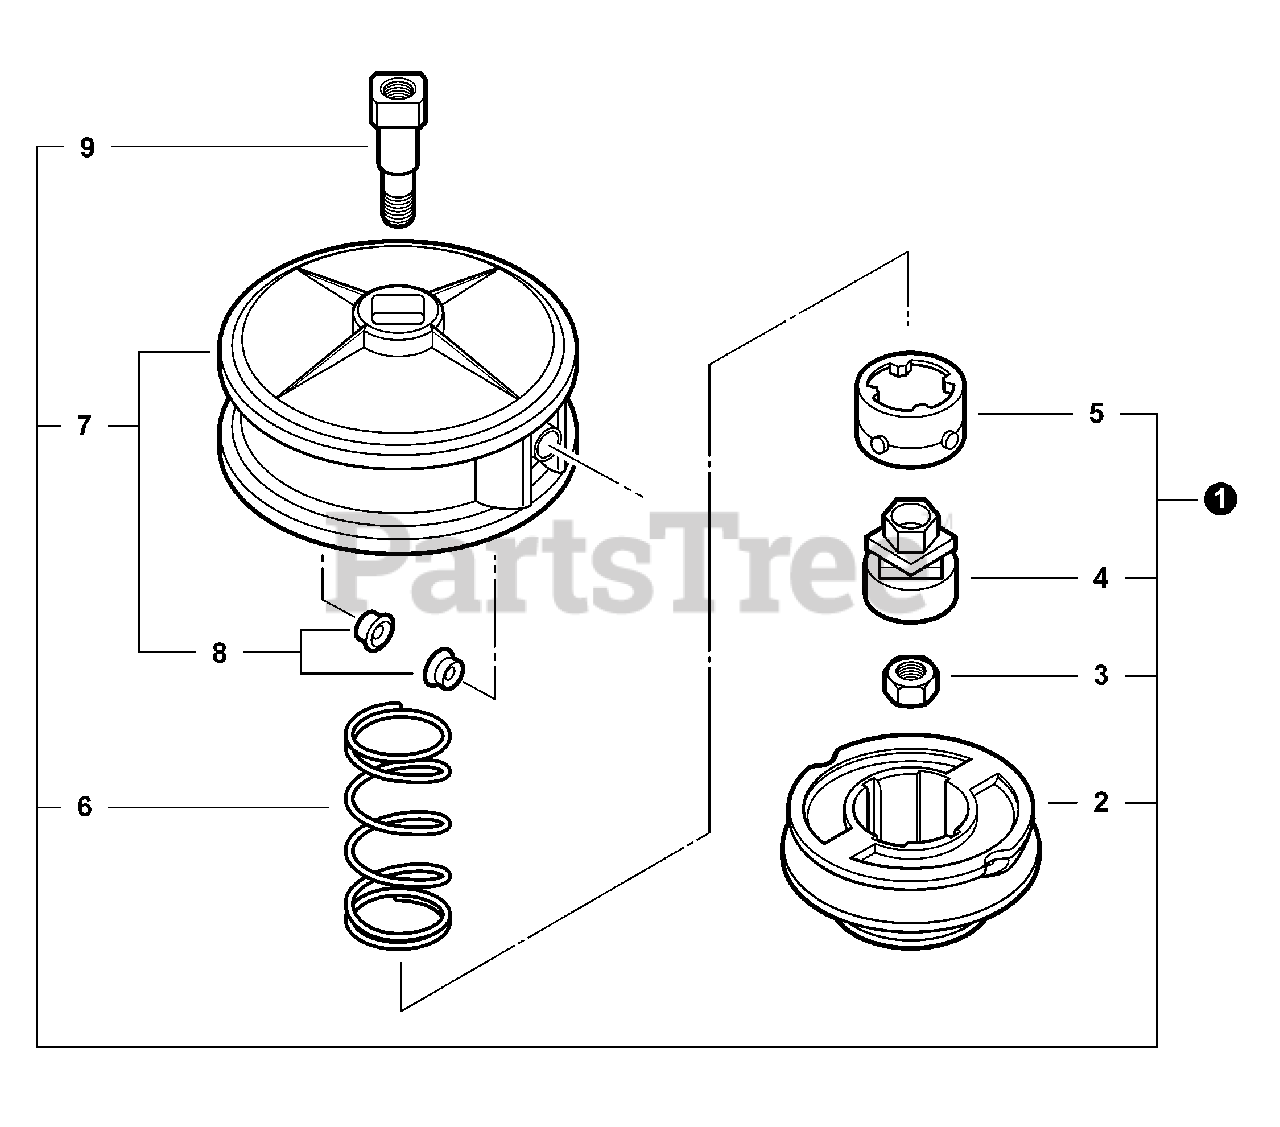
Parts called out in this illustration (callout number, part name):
1	TRIMMER HEAD, U-TURN
4	CAM, INNER
5	DRIVE, OUTER
7	HOUSING ASSY, SPOOL
9	STUD, ARBOR M10×1.25 LH
